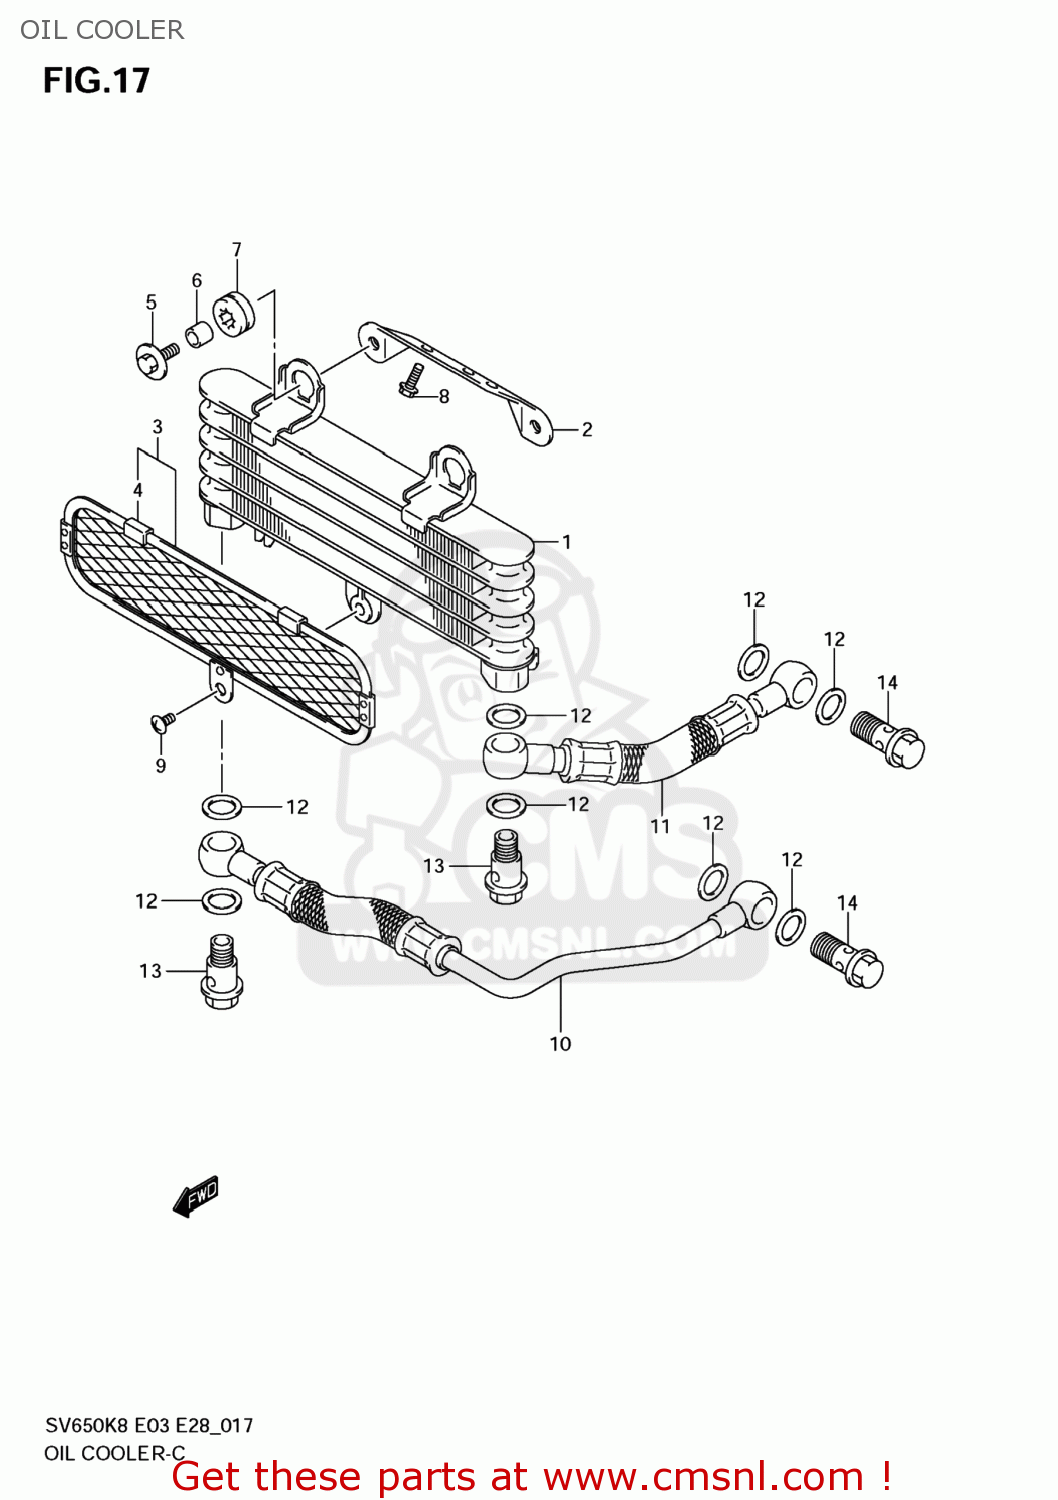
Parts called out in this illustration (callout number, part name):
1	COOLER ASSY,OIL
2	BRACKET,OIL COOLER
3	GUARD,OIL COOLER
4	PROTECTOR,CTR
5	BOLT(6X20)
6	SPACER(6.5X10X10)
7	CUSHION
8	BOLT
9	SCREW
10	HOSE,OIL COOLER,R
11	HOSE,OIL COOLER,L
12	GASKET(14X20X1.5) (NAS)
13	BOLT UNION
14	BOLT UNION
